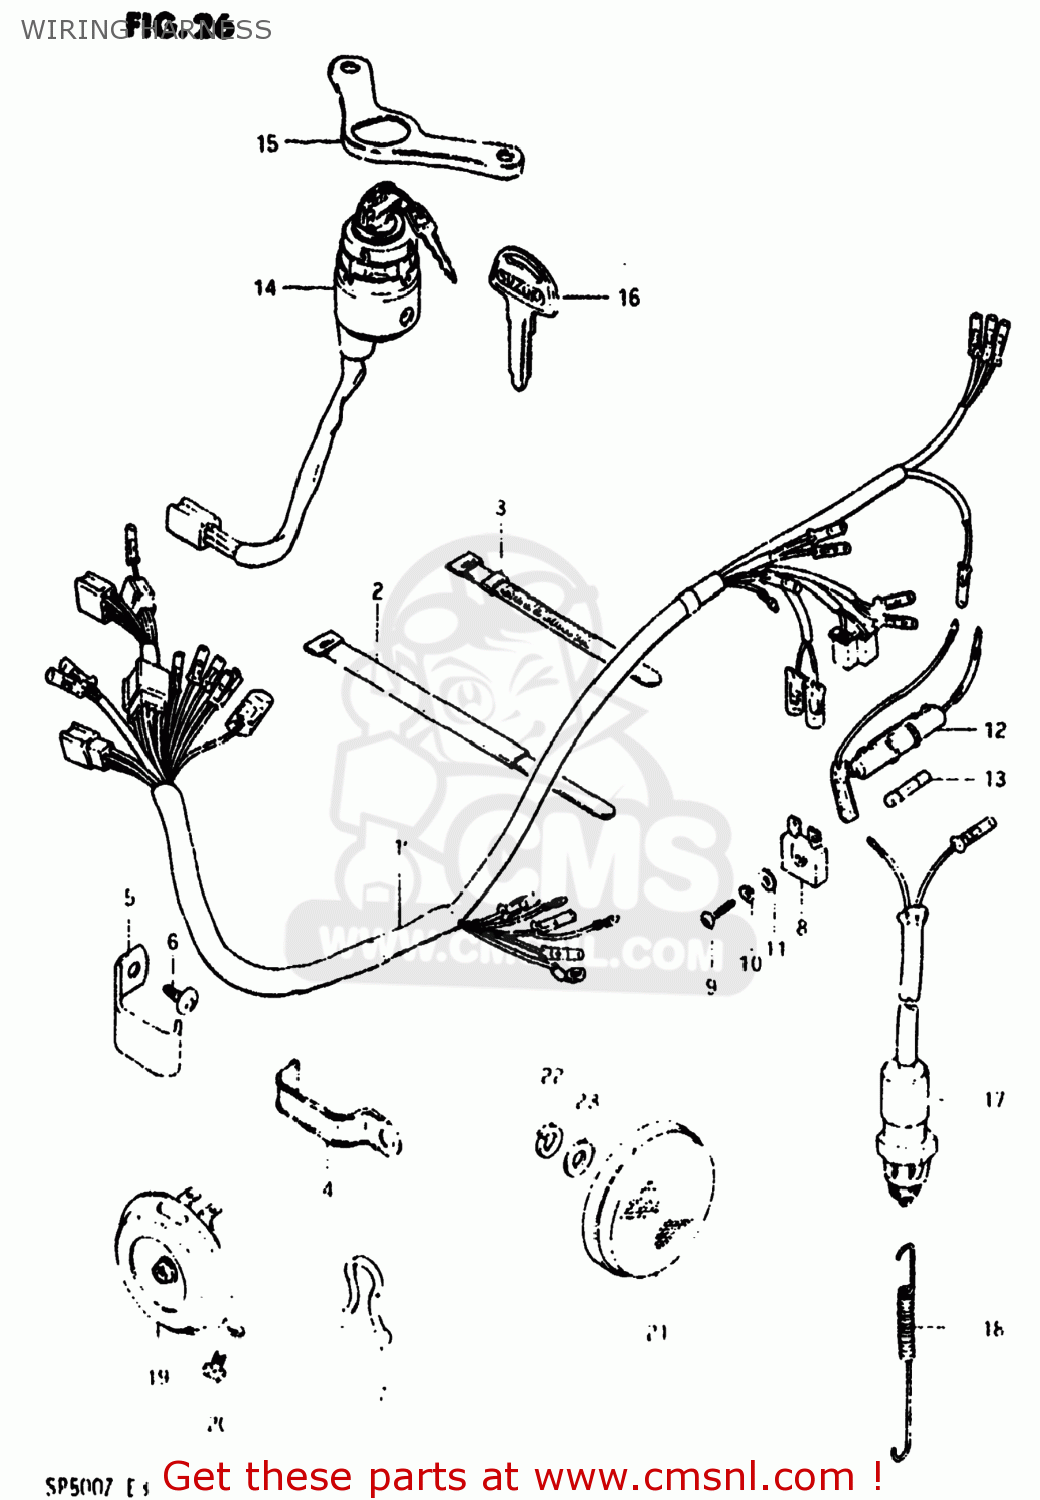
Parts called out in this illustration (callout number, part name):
1	HARNESS,WIRING
2	CLAMP
3	CLAMP(L:120)
4	CLAMP
5	CLAMP,WIRING HARNESS
6	SCREW
7	CLIP
8	RECTIFIER ASSEMBLY
9	SCREW 5X20
10	WASHER,LOCK
11	WASHER
12	BOX ASSEMBLY,FUSE
13	FUSE(15A)
14	SWITCH ASSY,IGNITION
15	BRACKET,IGNITION SWITCH
16	KEY,BLANK
17	SWITCH ASSEMBLY,STOP LAMP
18	SPRING
19	HORN ASSEMBLY
20	BOLT
21	REFLEX REFLECTOR,FR
22	LOCK WASHER
23	WASHER
